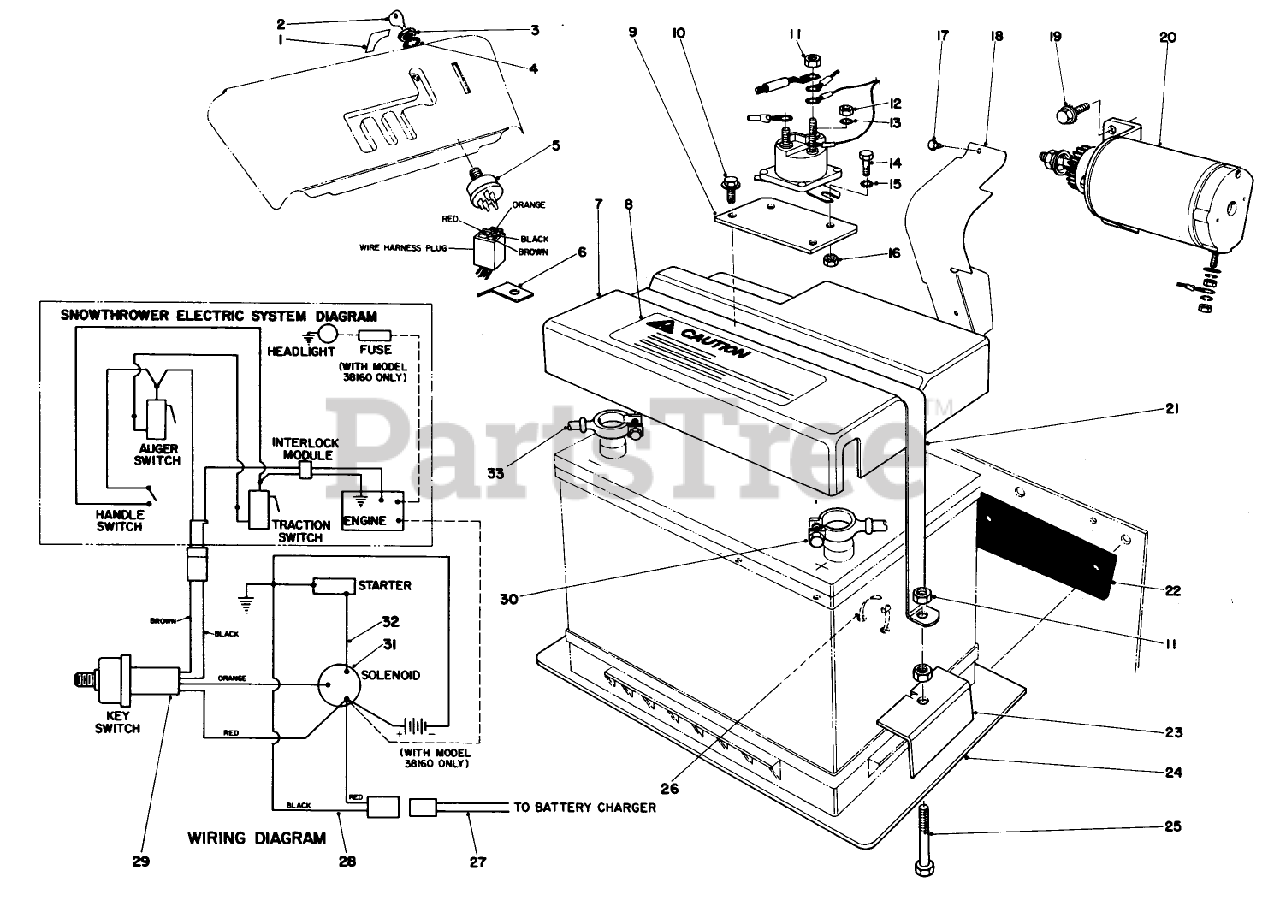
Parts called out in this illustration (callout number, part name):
3	NUT-HH
4	WASHER-LOCK
8	Decal-Caution
10	SCREW-HWH
11	NUT-HEX
12	NUT-HEX
13	WASHER-LOCK, INT
14	SCREW-HH
15	WASHER-LOCK/EXT
16	NUT-LOCK, NI
18	BRIGGS 280265
19	5/16-18X3/4 HX HD SEM
20	Starter Motor Pinion Assy.
25	SCREW-HH
26	TIE-CABLE
27	MALE WIRE ASM
29	Wire Harness
30	BATT-SOLENOID CABLE
31	SOLENOID
